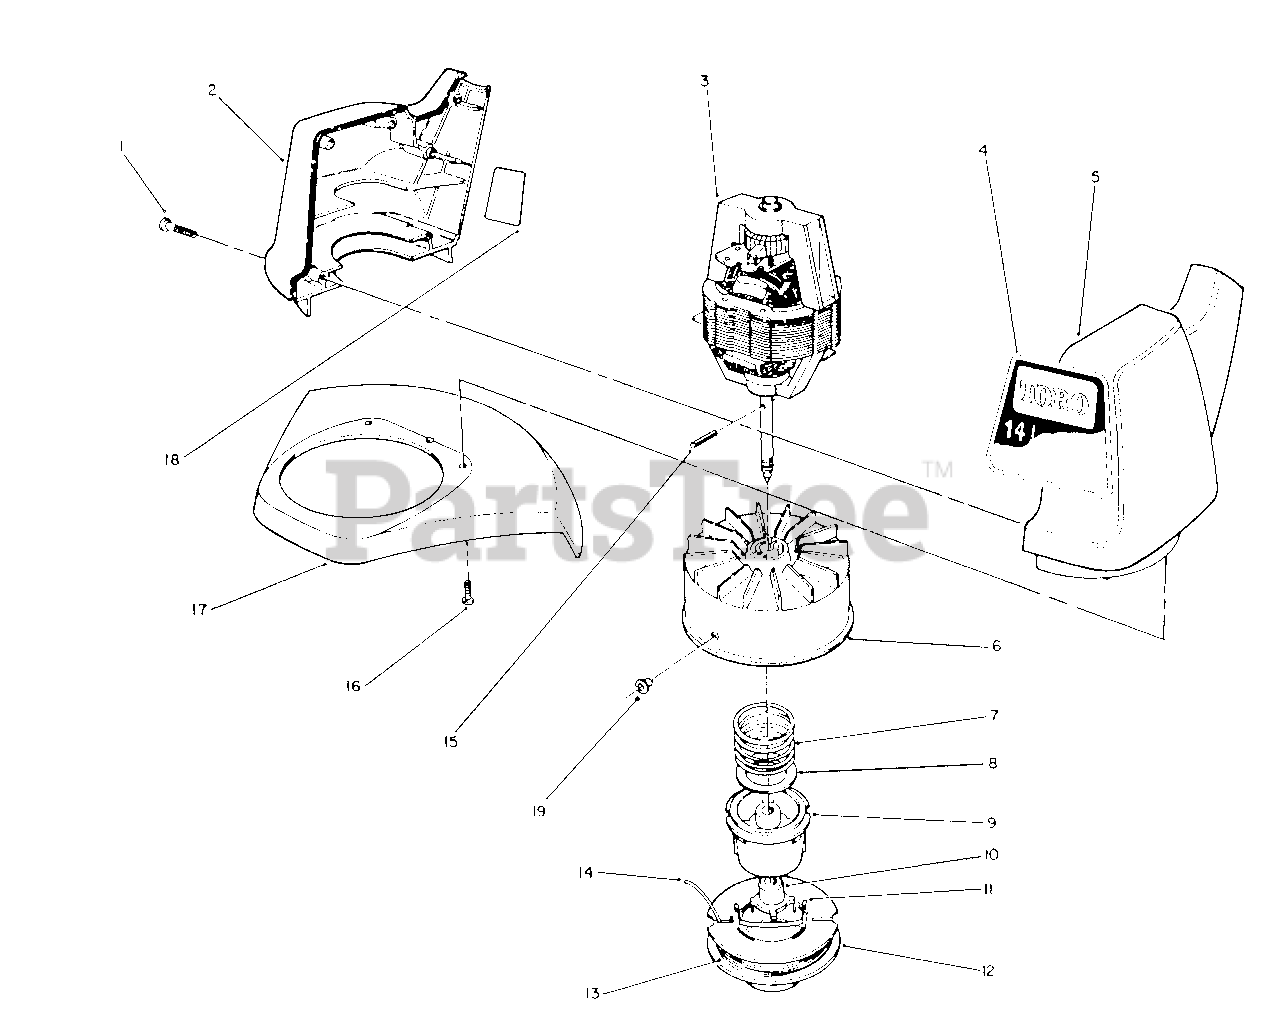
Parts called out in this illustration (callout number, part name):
1	Screw-Thread Forming
2	Housing-Motor R.H.
3	Motor-Electric
4	Decal-14"
5	Housing-Motor L.H.
6	Drum & Eyelet Assembly
7	Spring-Compression
9	Spool-Core
12	Empty Spool
13	50 Ft. Coil-.065 Dia. Cutting Line Prewound on Spool
14	50 Ft. Coil-.065 Dia. Cutting Line in Coil
15	Pin-Spiral
16	Screw-Thread Forming
17	Shield Assembly
18	Decal-Made In Canada
